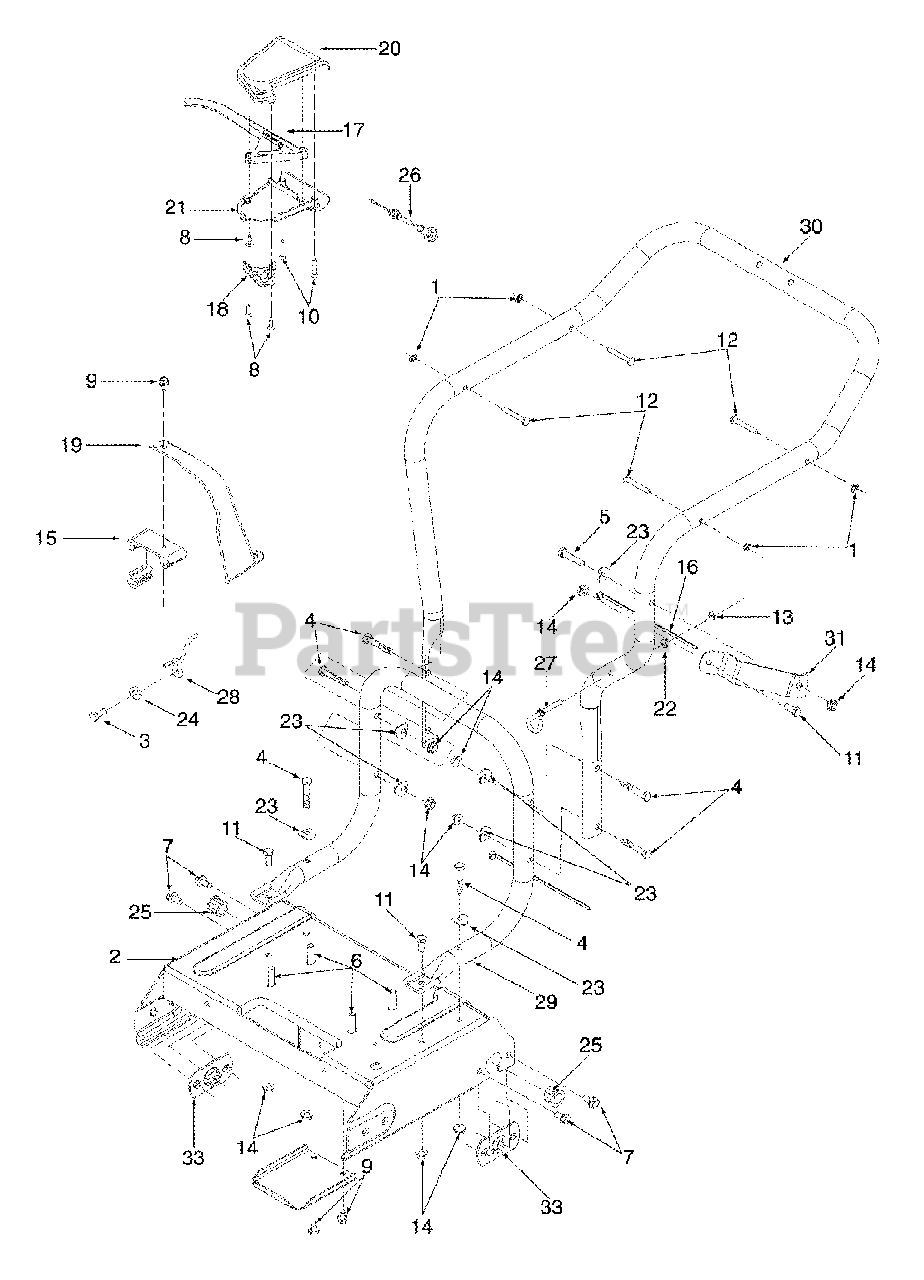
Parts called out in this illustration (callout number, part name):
1	PUSH NUT .250
3	HEX CAP SCREW 5/16-24 .75
4	HEX CAP SCREW 5/16-18 1.75
5	HEX CAP SCREW 5/16-18 1.50
6	SELF TAP SCREW 3/8-16 x 1.25
7	SELF TAP SCREW 5/16-18 x .62
8	SCREW #10-12 x .75
9	HEX SCREW 1/4-14 x .625
10	HEX LOCK SCREW 8-18 x 1.25
11	HEX CAP SCREW 5/16-18 x .75
12	STUD PIN .250 x 1.75
13	HEX NUT 1/4-28
14	HEX FLANGE LOCK NUT 5/16-18
15	ENGINE MOUNTING ADAPTER
17	DRIVE CONTROL LEVER
18	CABLE MOUNTING CAP
20	UPPER CLUTCH COVER
21	LOWER CLUTCH COVER
22	LOCK WASHER 1/4
23	SADDLE WASHER .320 id x .83 od
24	FLAT WASHER .344 x .750 x .120
25	FLANGE BEARING
26	CLUTCH CABLE 56.00
28	BELT KEEPER
